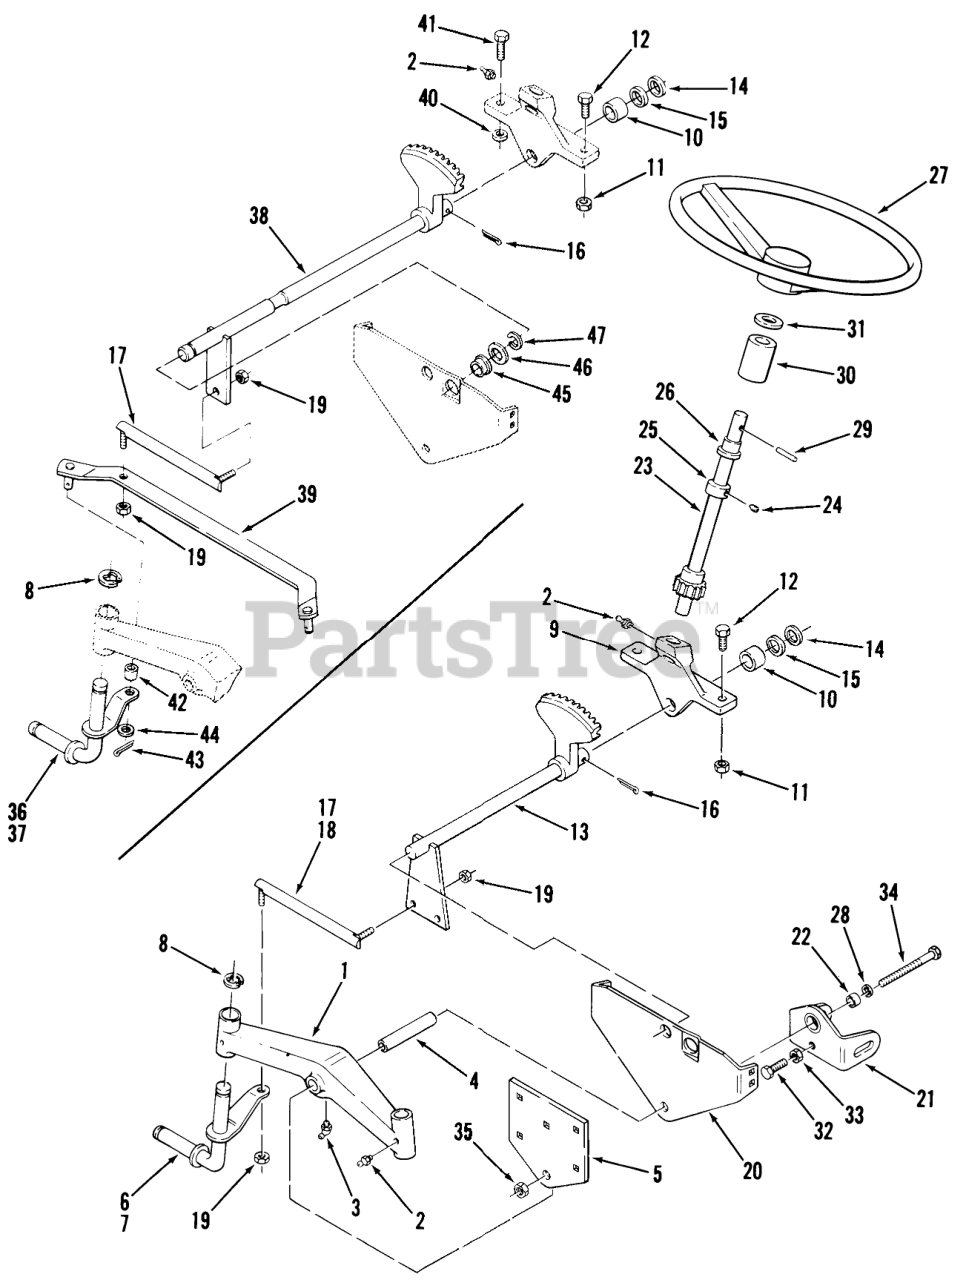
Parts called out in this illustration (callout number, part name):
1	AXLE-FRONT R
2	Zerk
3	FITTING-GREASE
4	SPACER-AXLE
5	Plate-Front Axle
6	Assy-Front Spdl RH
7	Assy-Front Spdl LH
8	Snap Ring
9	Support
10	BEARING-BRONZE
11	Nut
12	Bolt
13	ASSY-STRG SHFT LO R
14	WASHER-SHIM
15	WASHER
16	PIN-4
17	25LL JOINT ASSY R R
18	BALL JOINT ASSY L R
19	NUT-6
20	SUPPORT-AXLE
21	Front Hanger (Mower)
22	BUSHING
23	ASSY-STRG SHFT-UP R
24	SCREW-SET
25	Collar
26	BEARING
27	STEERING WH 13" PLAS
28	Washer
29	Pin-Roll
30	COLLAR
31	WASHER-BOWED
32	SCREW-HH
33	Nut
34	Bolt 1/2-13 X 5
35	Eslok Nut
36	Assy-Front Spdl RH B-165 Only
37	Assy-Front Spdl LH B-165 Only
38	Assy Strg Lower B-165 Only
39	ASSY-TIE ROD R
40	WASHER
41	BOLT
42	SPACER
44	WASHER
45	BUSHING
46	WASHER SPECIAL
47	Ring
